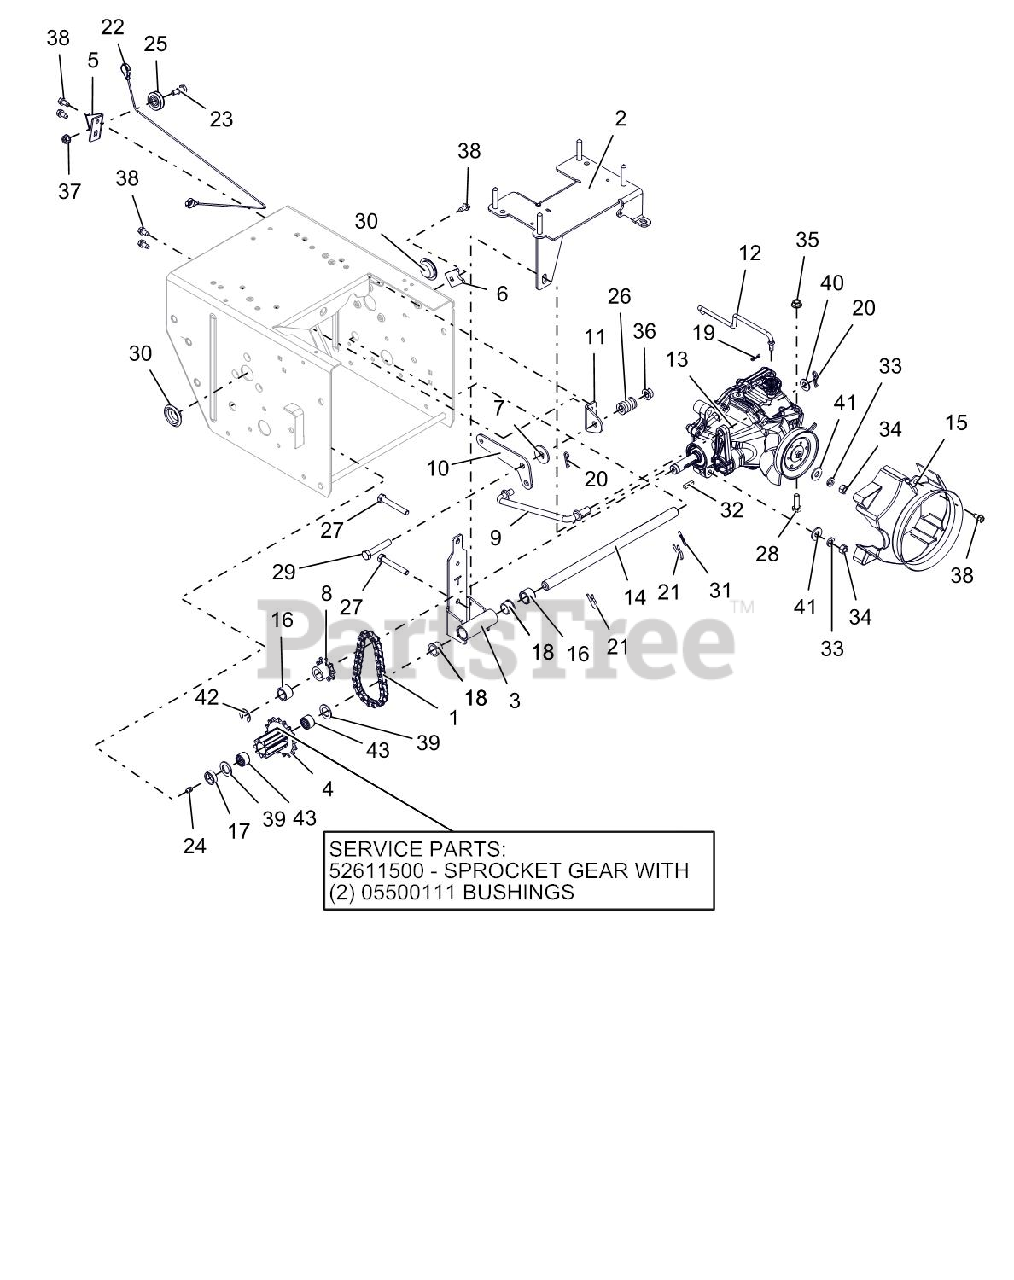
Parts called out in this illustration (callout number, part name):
1	CHAIN-ROLLER #41X26 PITCHES
2	BRACKET, HYDROSTATIC TRANS XLG
3	TRANS MOUNT, TENSIONING, TRACK
4	BSHG-FLG .625X.750X.500X.875
4	PINION & SPROCKET (16T & 9T)
4	PINION & SPROCKET W/BEARINGS
5	BRACKET, CABLE PULLEY
6	TAB, ANTI ROTATION
7	FRICTION WASHER
8	SPROCKET, PINION 9T W/KEY
9	ROD, HYDRO TRANS SHIFT
10	PIVOT, HYDRO TRANS SHIFT
11	BRACKET, HYDRO SHIFT PIVOT
12	ROD, HYDRO BYPASS
13	TRANSMISSION, HYDROSTATIC
14	SHAFT, PINION - HARDENED
15	SHROUD, HYDROGEAR RT-310
16	SPACER, .635X.880X.611
17	BSHG-SLV, .635X.880X.305
18	BSHG-FLG .625X.750X.500X.875
19	PIN-HAIR INT .06X.18X.77
20	PIN-HAIR INT .08X.18X1.18 YWZC
21	PIN, SPRING CLIP
22	CABLE, TRACTION, HYDRO PRO
23	BOLT, SHLDR-.375X.375X.25-20
24	ZERK,FITTING .25X.125 DRIVE IN
25	PULLEY, CABLE
26	SG-COMP .187X.56X1.62
27	@BLT-HEX .31-18X2.25 GR5 YWZC
28	@BLT-HEX .31-18X1.00 GR5 YWZC
29	@BLT-HEX .38-16X2.00 GR5 YWZC
30	PLUG, HOLE - 1.125"
31	@PIN-GRV .125X1.00 TP E ALLOY
32	KEY-SQ .188X.75X.188
33	WSHR-LK .312X.097 HVY YWZC
34	@NUT-HEX .31-18 YWZC
35	@NUT-LK-TOP-FLG .31-18 YWZC
36	@NUT-LK-TOP-FLG .38-16 YWZC
37	@NUT-LK-TOP-FLG .25-20 YWZC
38	SCR-TAP .25-20X.50 HWH TR YWZ
39	WSHR-FL-STL .630X1.005X.062 YZ
40	@WSHR-FL-STL.406X.812X.065 YWZ
41	@WSHR-FL-STL.38X.875X.083 YWZC
42	RG-RTNG-EXT .625X.042
43	BRG-NEEDLE .625X.812X.50
